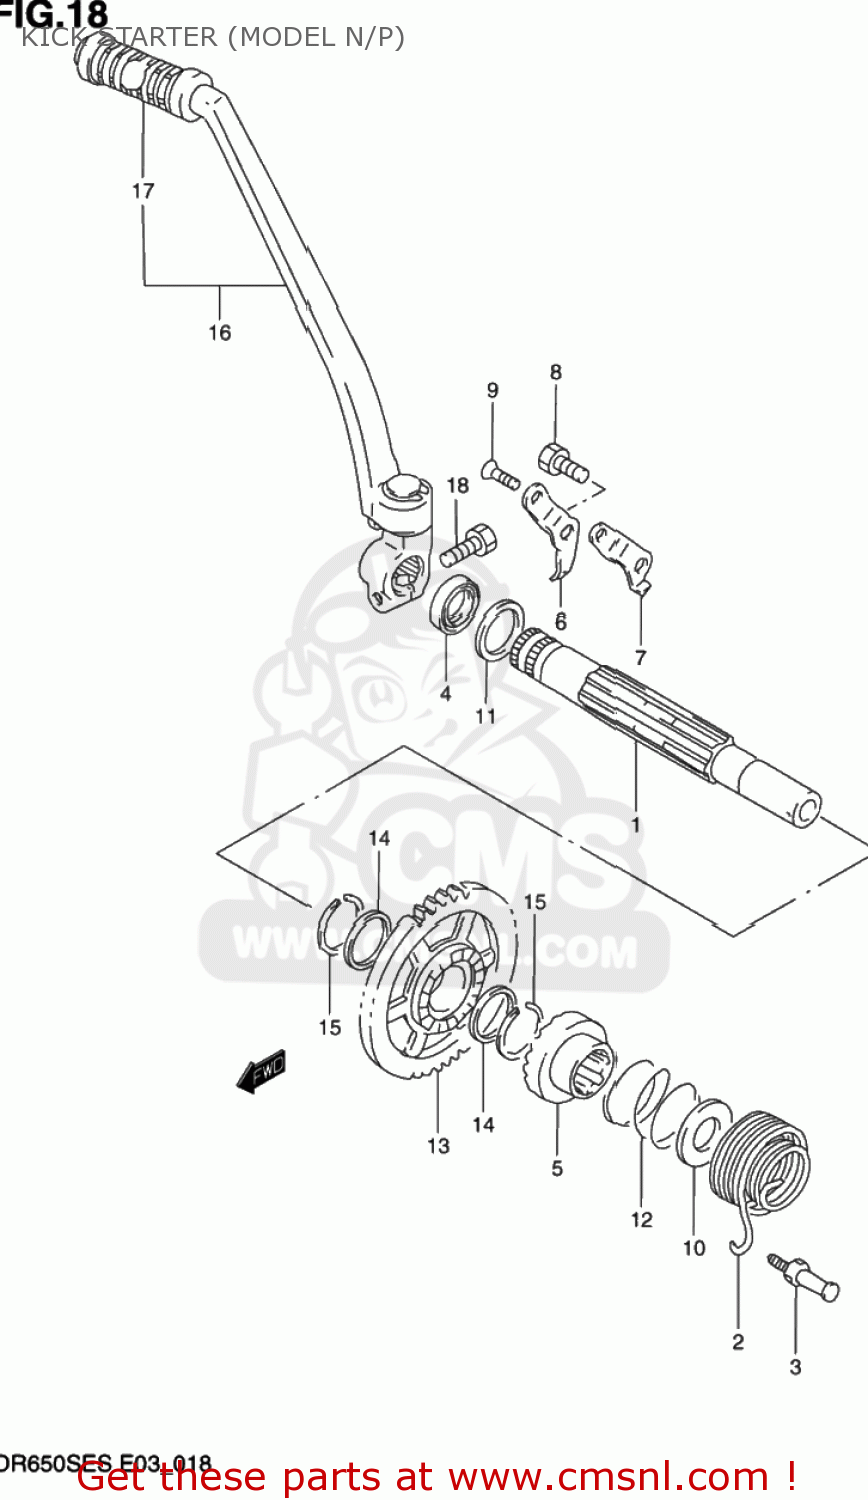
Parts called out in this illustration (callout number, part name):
1	SHAFT,KICK STARTER
2	SPRING
3	BOLT,KICK SHAFT SPRING
4	SEAL,OIL(20X27X6)
5	STARTER,KICK
6	GUIDE,KICK STARTER
7	STOPPER,KICK STARTER
8	BOLT,8X1.25X2
9	SCREW
10	WASHER
11	WASHER,THRUST
12	SPRING
13	GEAR,KICK STARTER DRIVE
14	SHIM
15	CIRCLIP
16	LEVER ASSY,KICK STARTER
17	RUBBER,KICK STARTER PEDAL
18	BOLT 8X25
